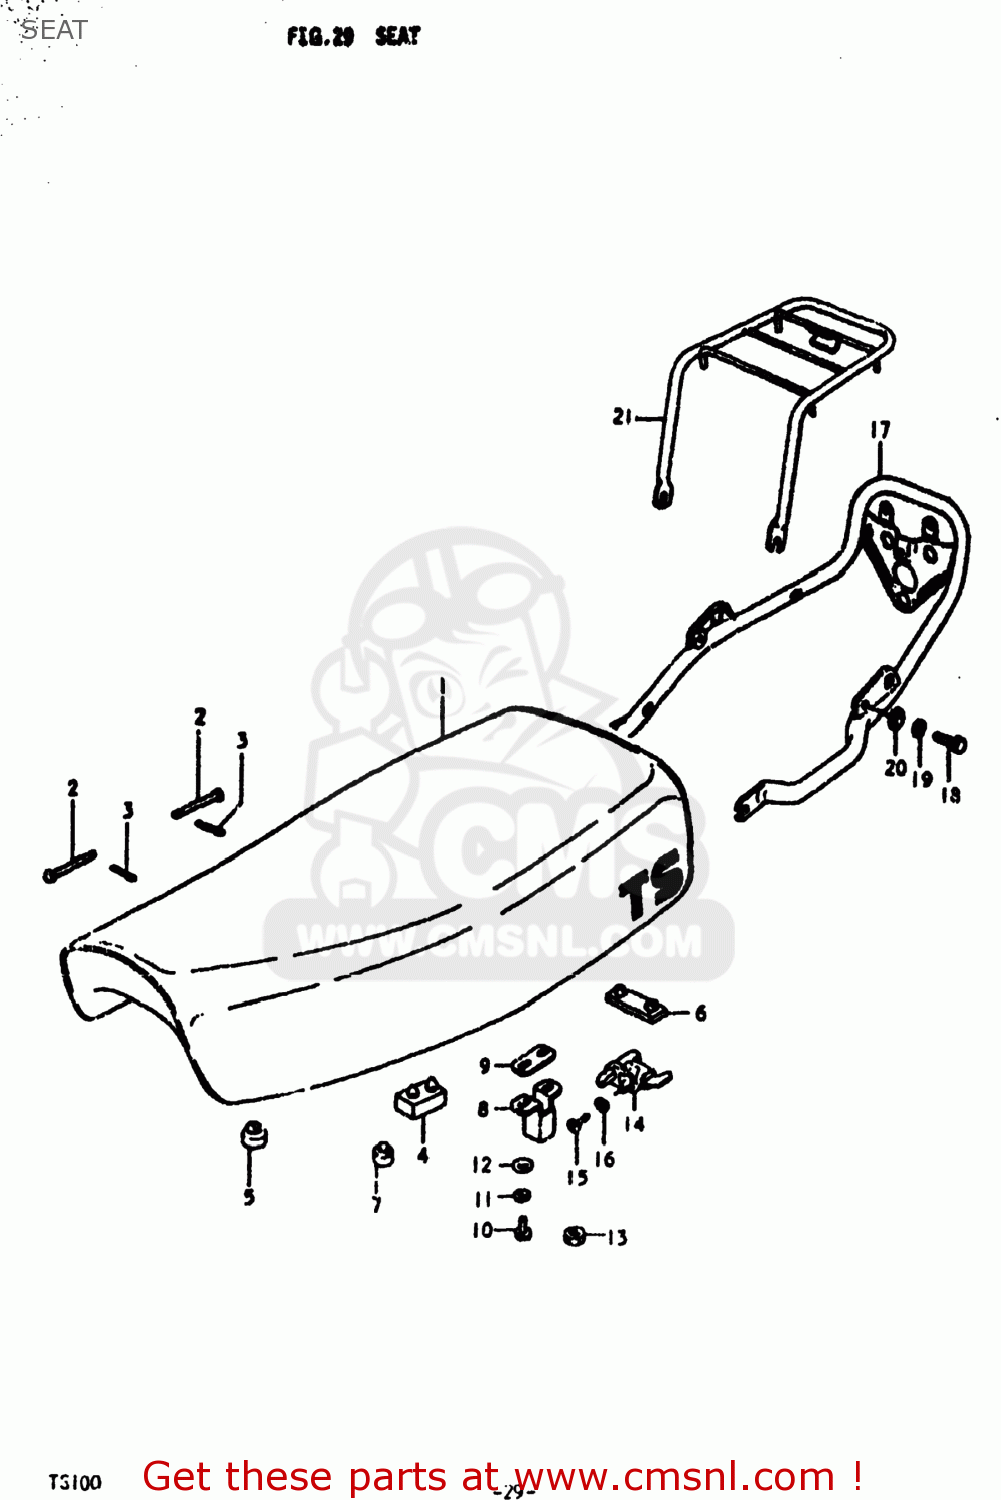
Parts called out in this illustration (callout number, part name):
1	SEAT ASSEMBLY
2	PIN
3	COTTER PIN
4	CUSHION
5	CUSHION(11.5X22X20)
6	CUSHION
7	CUSHION
8	PLATE,CLAMP GUIDE
9	WASHER(8.5X18X1)
10	BOLT
11	LOCK WASHER
12	WASHER
13	NUT
14	LOCK ASSY,SEAT
15	SCREW
16	LOCK WASHER
17	BRACKET,REAR TURN SIGNAL
18	BOLT,8X1.25X2
19	LOCK WASHER
20	WASHER
